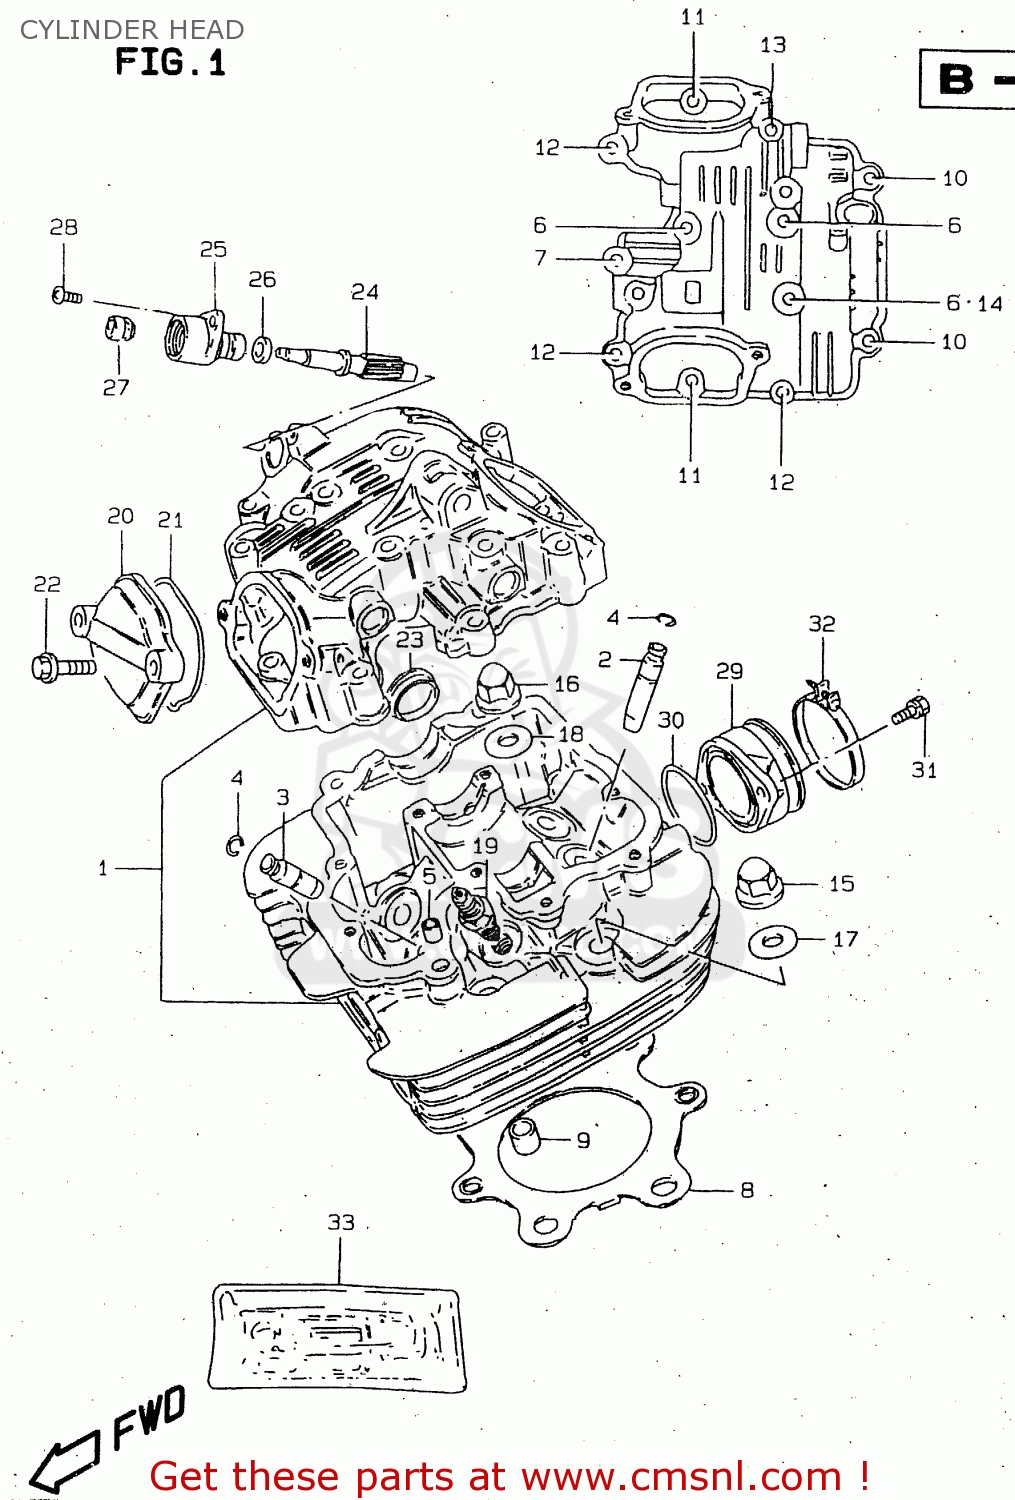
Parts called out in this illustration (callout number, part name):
1	HEAD,CYLINDER
2	GUIDE,INTAKE VALVE
3	GUIDE,VALVE
4	RING,SNAP
5	PIN(6.2X8X11)
6	BOLT
7	BOLT
8	GASKET,CYLINDER HEAD (NAS)
9	PIN
10	BOLT(6X115)
11	BOLT
12	BOLT
13	BOLT
14	GASKET(5.8X13X1.2) (NAS)
15	NUT
16	NUT
17	WASHER (10.5X22X2.3)
18	GASKET(10.5X22X2) (NAS)
19	SPARK PLUG D8EA
20	CAP,INSPECTION
22	BOLT
23	PLUG(OD:30)
24	GEAR,TACHOMETER DRIVEN
25	SLEEVE,TACHOMETER DRIVE GEAR
26	SEAL,TACHOMETER DRIVEN
27	SEAL,OIL(5X12X8)
28	SCREW(5X12)
29	PIPE,INTAKE
30	O RING(D:2.4,ID:39.7)
31	SCREW
32	CLAMP
33	GASKET SET
